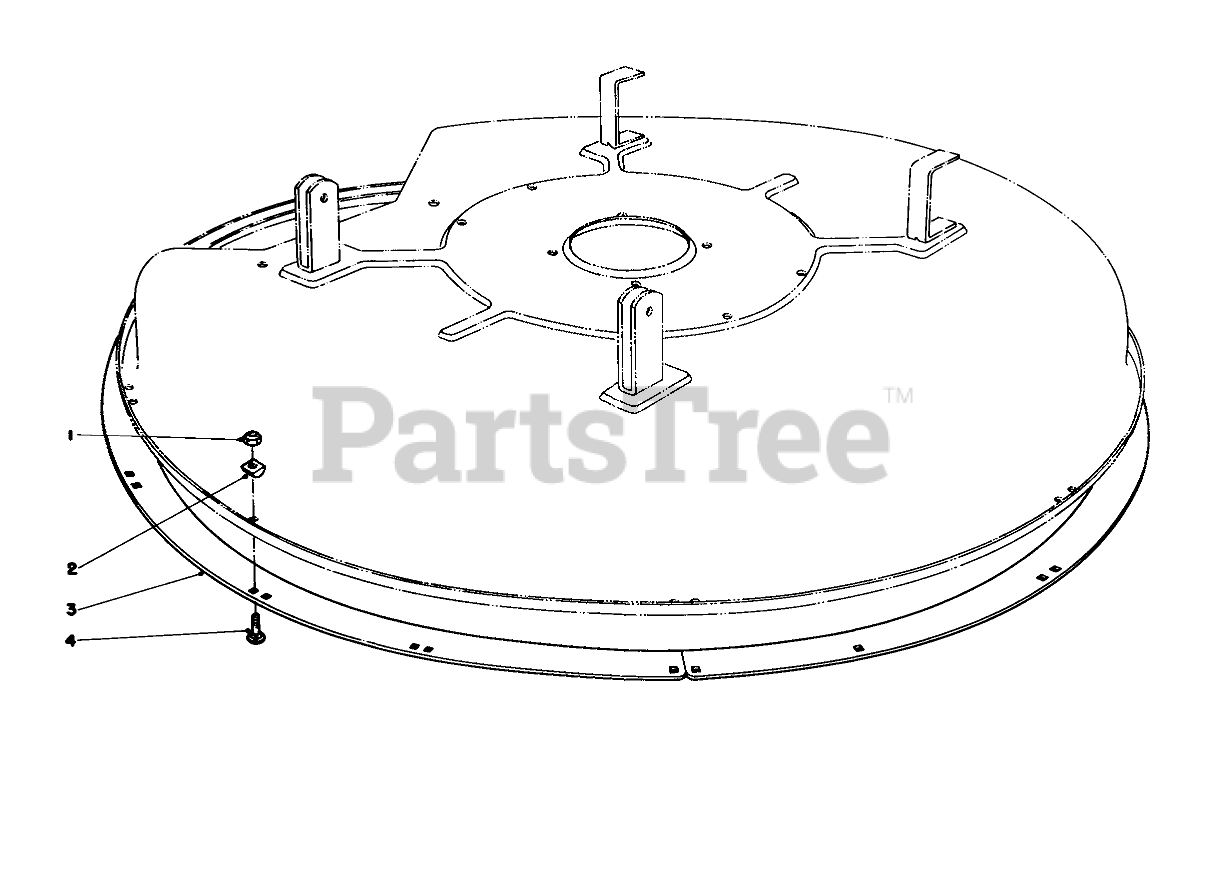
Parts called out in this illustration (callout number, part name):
1	NUT-LOCK, NI
2	Spacer-Deck Ring
3	DECK RING B
4	BOLT-CARR
